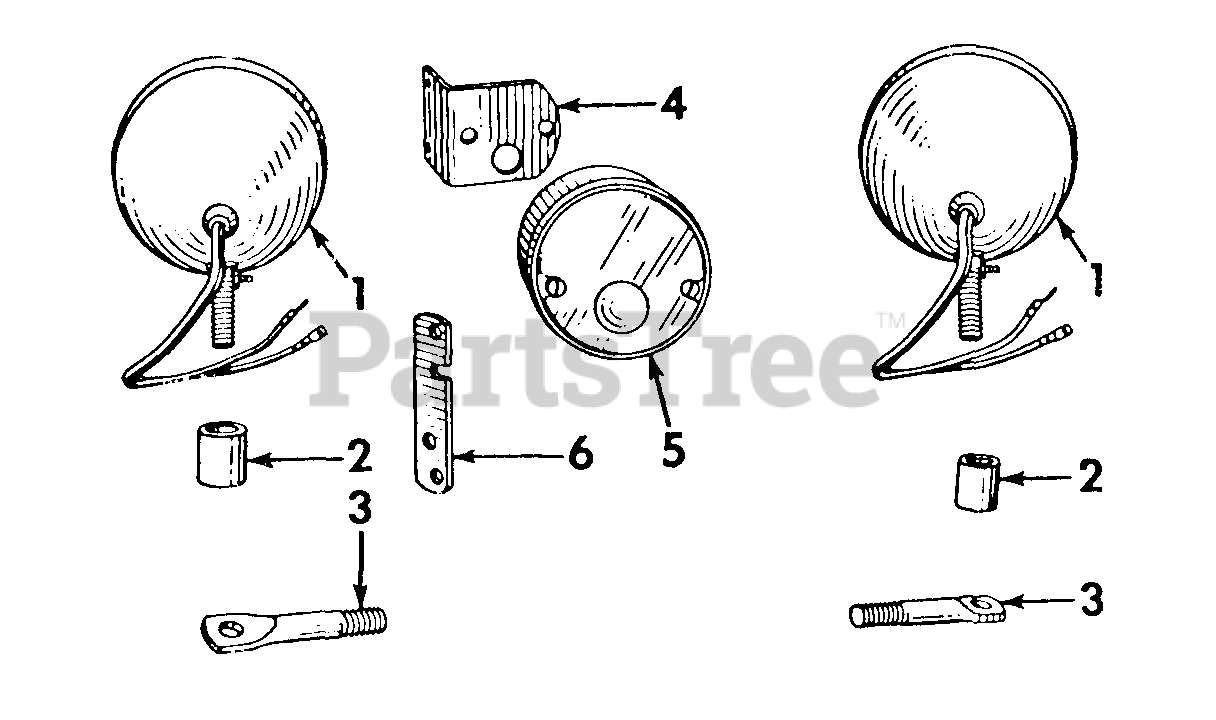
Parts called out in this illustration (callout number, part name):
1	LIGHT ASSY. HEAD OR REAR
2	SPACER, HEAD LIGHT
3	POST, HEAD LIGHT
4	BRACKET, TAIL LIGHT
5	LIGHT ASSY. TAIL
6	BRACKET, TAIL LIGHT
